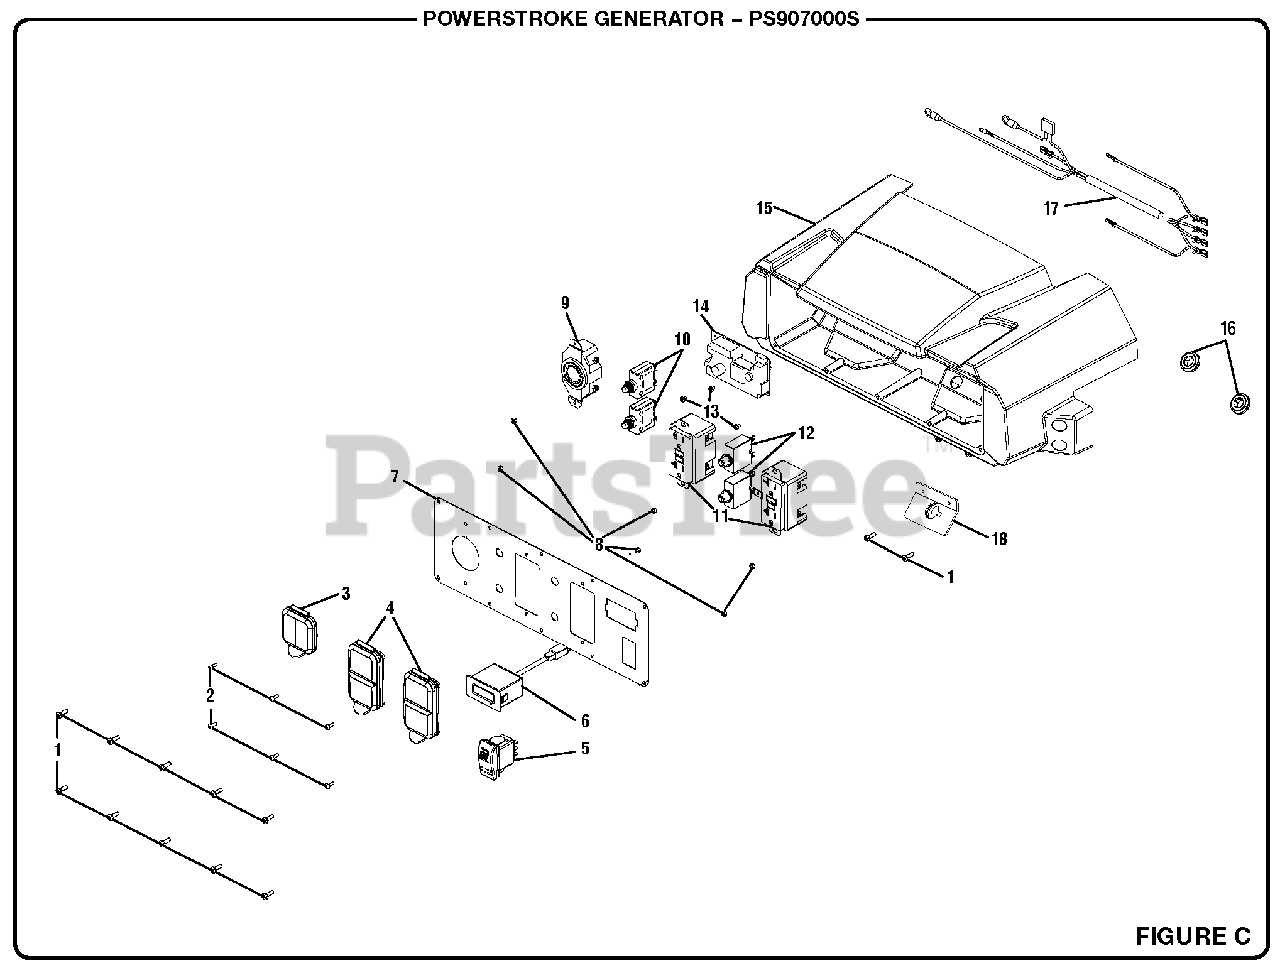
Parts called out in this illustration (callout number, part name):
1	Screw (#8-18 x 1/2 in., T20 Torx Pan Hd.)
2	Screw (#6-20 x 3/8 in., T15 Torx Pan Hd.)
3	240 Volt Outlet Cover
4	120 Volt Outlet Cover
5	Start Switch w/Lock
6	4 in 1 Digital Meter
7	Front Panel
8	Hex Nut (#6-32)
9	Twist Lock Receptacle (120/240 Volt, 30 Amp)
10	Circuit Breaker (30 Amp)
11	120 Volt Duplex Receptacle
12	Circuit Breaker (20 Amp)
13	Screw (M3 x 5 mm, T10 Torx Pan Hd.)
14	Battery Charger
15	Control Box Housing
16	Rubber Grommet
17	Wire Harness
18	Fuel Valve Bracket
